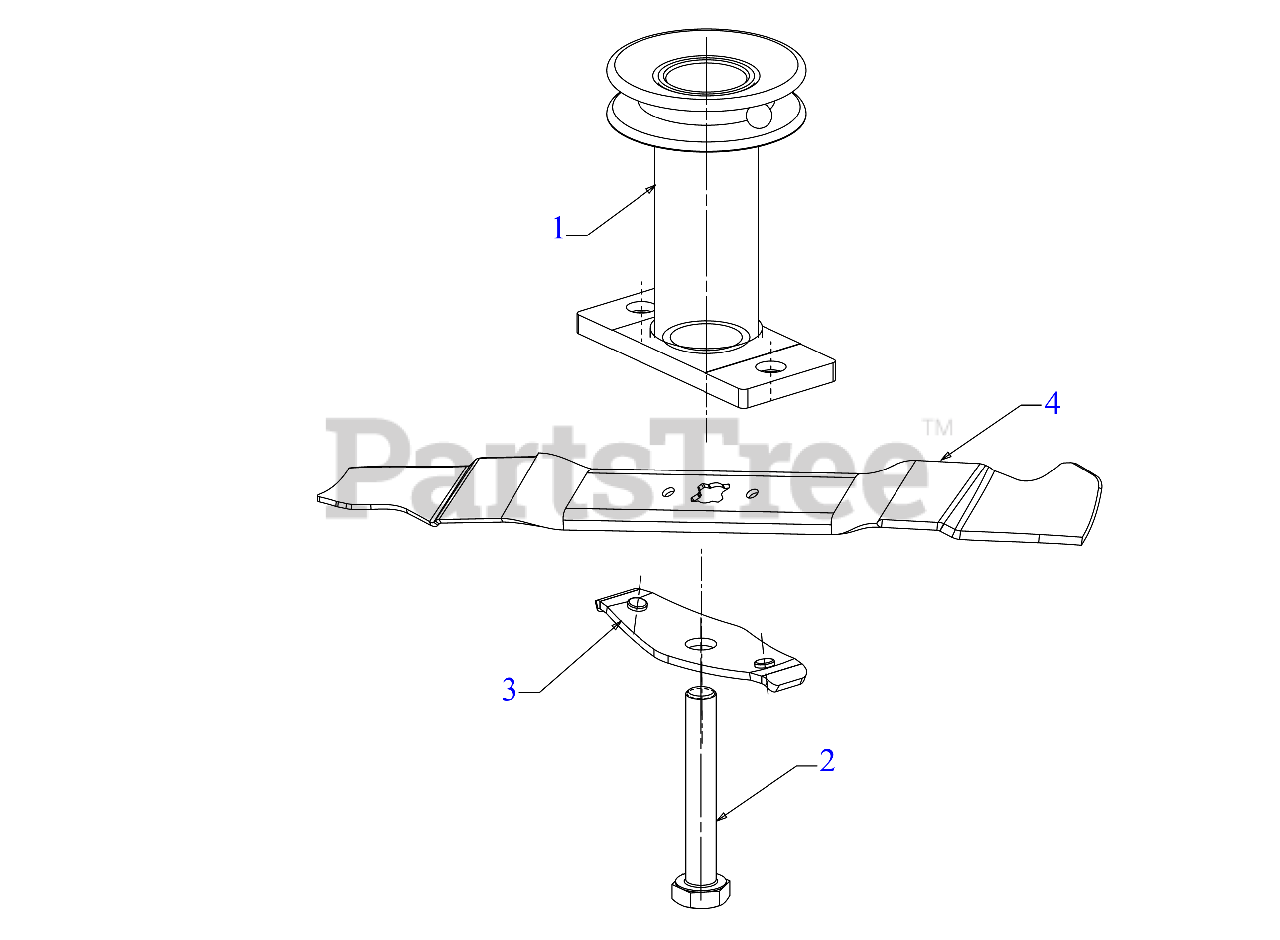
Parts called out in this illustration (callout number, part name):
1	BLADE ADAPTER (25MM x .430)
2	SCREW 3/8-24 x 2.50 GR8
3	BLADE BELL SUPPORT
4	23" BLADE (3N1)
